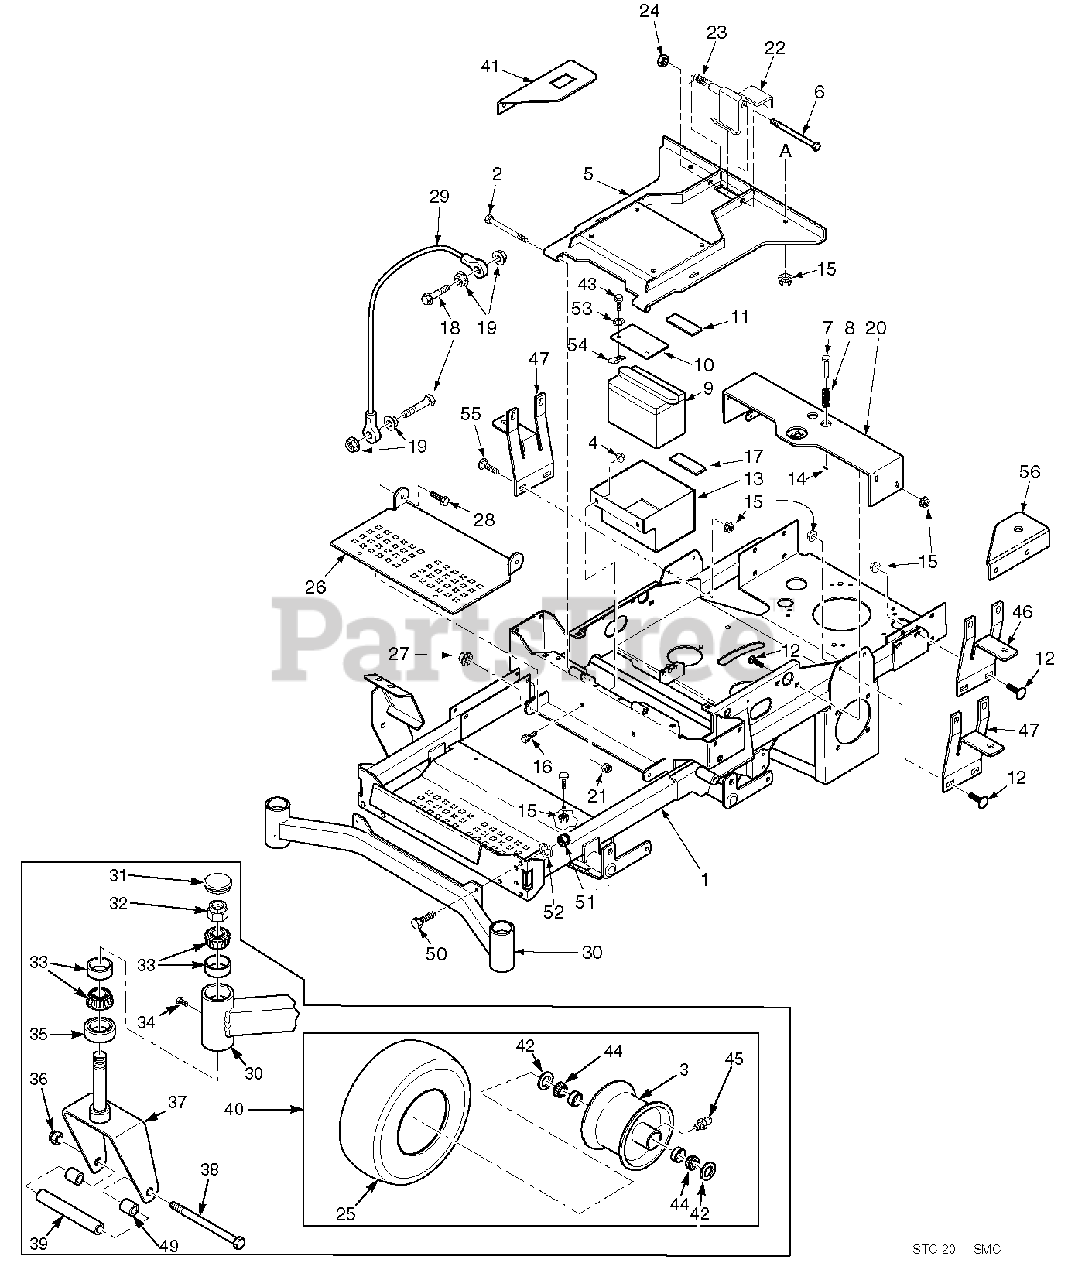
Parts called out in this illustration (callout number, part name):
1	Main Frame Assembly w/decals
2	Bolt, Hex Head 5/16-18 x 3-3/4"
3	Rim
4	Nut, Serr. Flange 3/8-16
5	Plate, Seat Mounting w/decals
6	Bolt, Hex Head 3/8-16 x 6"
7	Pin Retainer, Spring
8	Spring
9	Battery
10	Battery Cover
11	Battery Hold Down Pad
12	Bolt, Carr. 5/16-18 x 3/4"
13	Battery Box
14	Roll Pin, Spring 5/32 x 3/4"
15	Nut, Serr. Flange 5/16-18
16	Bolt, Hex Head 3/8-16 x 1"
17	Pad, Rubber
18	Bolt, Hex Head 1/4-20 x 1-1/4"
19	Nut, Serr. Flange 1/4-20
20	Seat Base Support
21	Nut, Elastic Stop 5/16-18
22	Seat Latch Weldment
23	Spring, Seat Latch
24	Locknut, 3/8-16 Center Lock
25	Tire, 13 x 5.0-6 Smooth
25	Tire, 13 x 6.5-6 Smooth
26	Footplate
27	Nut, Elastic Stop 3/8-16
28	Bolt, Hex Head 3/8-16 x 1"
29	Cable, Seat Stop
30	Weldment, Caster Support
31	Cap, Grease
32	Nut, Elastic Stop 1.0"-14
33	Bearing Set
34	Plug, 1/4-28
35	Seal, 2.0" OD x 1.625" ID
36	Nut, Elastic Stop 1/2-13
37	Yoke, Front Caster Wheel
38	Bolt, Hex Head 1/2-13 x 7-1/2"
38	Bolt, Hex Head 1/2-13 x 9-1/2"
39	Sleeve
40	Caster Wheel Assembly
41	Bracket, Hour Meter
43	Bolt, Hex Head 3/8-16 x 1-1/4"
44	Roller Bearing
45	Fitting, Grease
46	Mounting Bracket, Oil Tank
47	Mounting Bracket, Fuel Tank
48	Seat Pan
49	Spacer, Caster Wheel
50	Bolt, Hex Head 7/16-14 x 1-1/4"
51	Nut, Elastic Stop 7/16-14
52	Lockwasher, 7/16"
53	Lockwasher. 3/8" Spring
54	U-Nut, 3/8-16
55	Bolt, Carriage 5/16-18 x 1"
56	Bracket, Fuel Valve
